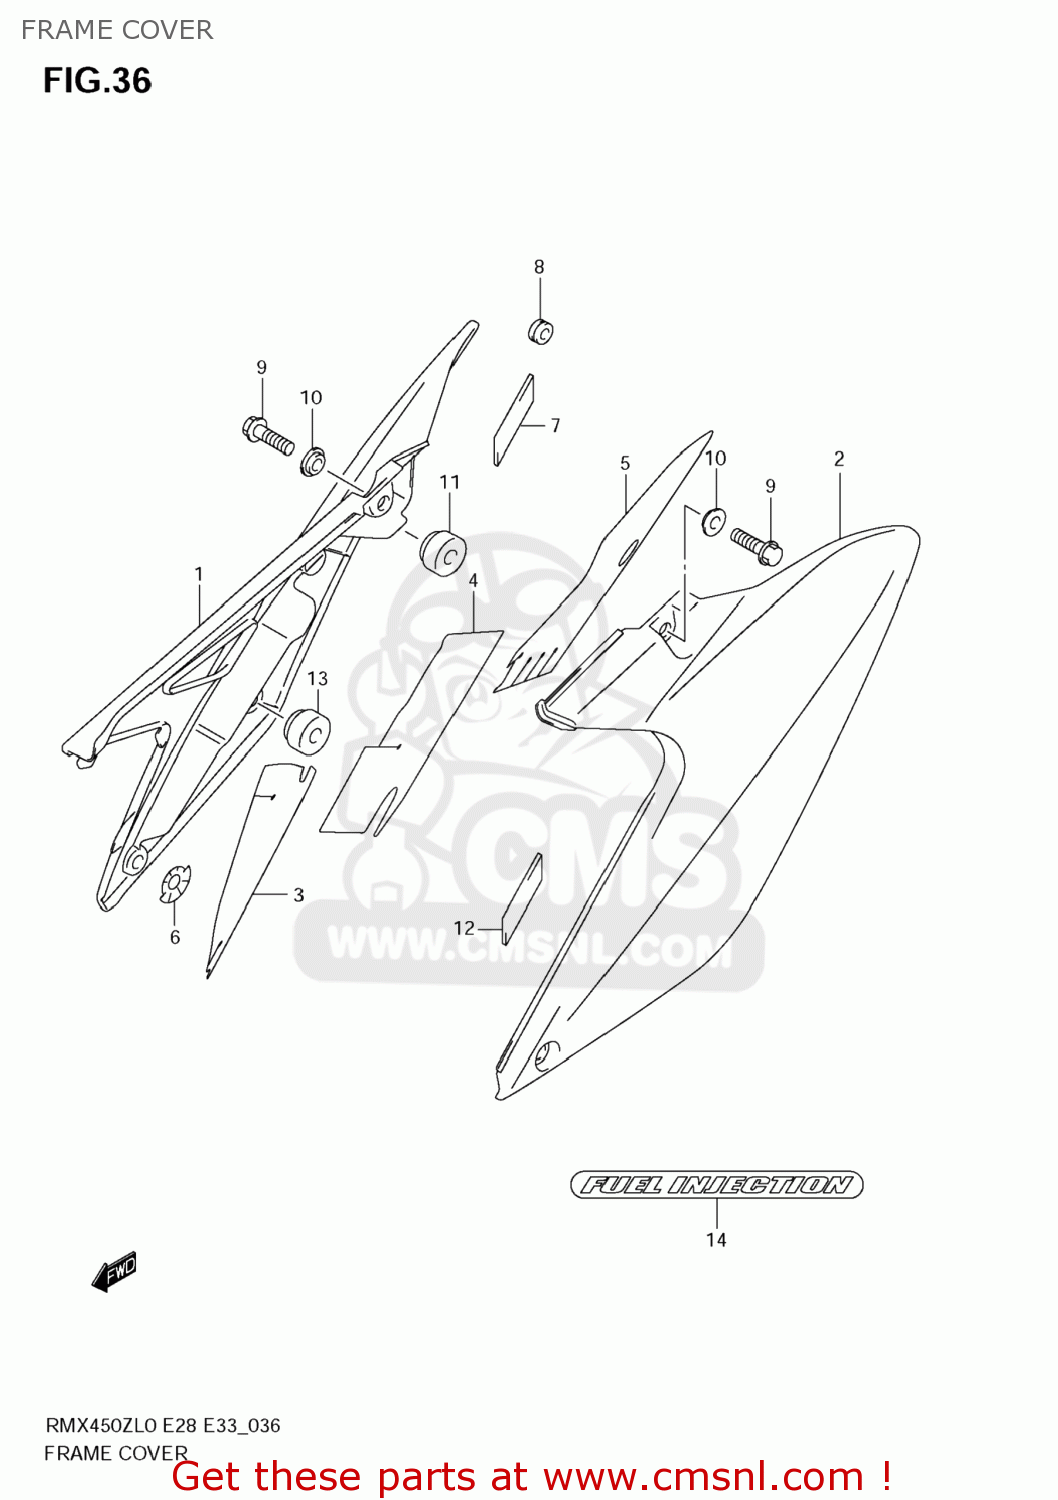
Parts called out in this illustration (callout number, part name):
1	COVER,FRAME,R(WHITE)
2	COVER,FRAME,L(WHITE)
3	SHIELD,FRAME COVER,R NO.1
4	SHIELD,FRAME COVER,R NO.2
5	SHIELD,FRAME COVER,R NO.3
6	SHIELD,FRAME COVER,R NO.4
7	CUSHION
8	CUSHION
9	BOLT
10	WASHER,FUEL TANK COVER
11	CUSHION
12	CUSHION,FRAME COVER,L
13	CUSHION
14	EMBLEM,FRAME COVER
